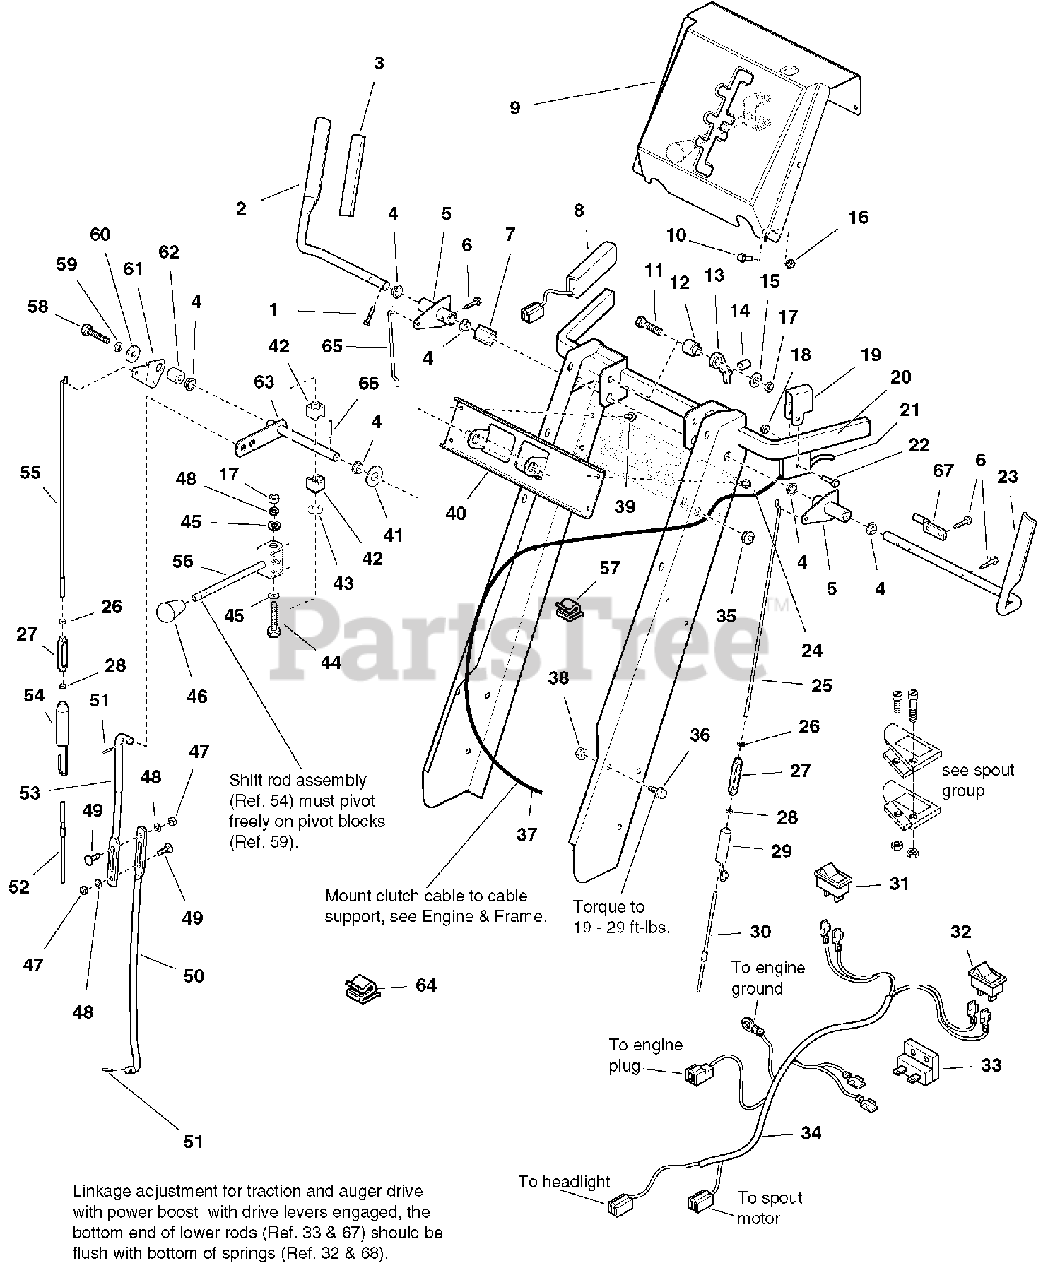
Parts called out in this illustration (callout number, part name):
1	CAPSCREW, Hex Washer Head, #10-24 x 1
2	HANDLE, Clutch, RH
4	BUSHING, Nylon
5	LEVER & TUBE ASSEMBLY, Clutch
6	CAPSCREW, Hex Washer Head, #12-24 x 1
7	GUIDE, Control
8	GRIP, Heated
10	CAPSCREW, Hex Head, 1/4-20 x 3/4
11	CAPSCREW, Hex Head, 5/16-18 x 1 1/2
12	SPACER
13	LATCH, Control
14	SPRING, Compression
15	WASHER, 5/16
16	NUT, Hex Lock, 1/4-20
17	NUT, Hex, Center Lock, 5/16-18
18	NUT, Hex Lock, #10-24
19	CLAMP, Clutch Cable
20	HANDLE ASSEMBLY
21	TRIGGER ASSEMBLY, Easy Turn Clutch Cable
22	SCREW, Pan Head, Phillips, #10-24 x 1
23	HANDLE, Clutch
24	CAPSCREW, Hex Head, Taptite, 1/4-20 x 1/2
26	NUT, LH, Machine Screw, Hex, #10-24
28	NUT, RH, Machine Screw, Hex, #10-24
30	ROD, Clutch
31	SWITCH, Rocker, Spout Rotator
32	SWITCH, Hand Warmer, Off, Warm, Hot
33	RESISTOR BLOCK
34	HARNESS Assembly
36	CAPSCREW, Hex Whiz Lock, 5/16-18 x 3/4
37	CABLE & HANDLE ASSEMBLY, Clutch (Includes Ref. 21)
38	NUT, Hex Flange, 5/16-18
39	CAPSCREW, Hex Washer Head, 1/4-20 x 5/8
40	BRACKET, Shift Control
41	WASHER, 1/2
42	BLOCK, Pivot
43	WASHER, Curved, 1/2
44	CAPSCREW, Hex Head, 1/4-20 x 2 1/4
45	WASHER, 1/4
47	NUT, Hex, 1/4-20
48	LOCKWASHER, Spring, 1/4
49	CARRIAGE BOLT, 1/4-20 x 3/4
50	ROD, Shift, Lower
51	PIN, Cotter
52	ROD, Clutch, Lower
53	ROD, Shift, Upper
55	ROD, Clutch, Upper
56	SHIFT ASSEMBLY, Rod & Clevis
57	CLIP, Wire
58	CAPSCREW, Hex Head, 5/16-18 x 3/4
59	LOCKWASHER, Spring, 5/16
60	WASHER, 5/16
61	LEVER, Clutch
63	ROD & ARM ASSEMBLY, Pivot
65	ROD, Clutch
66	PIN, Cotter
67	ROD, Control
